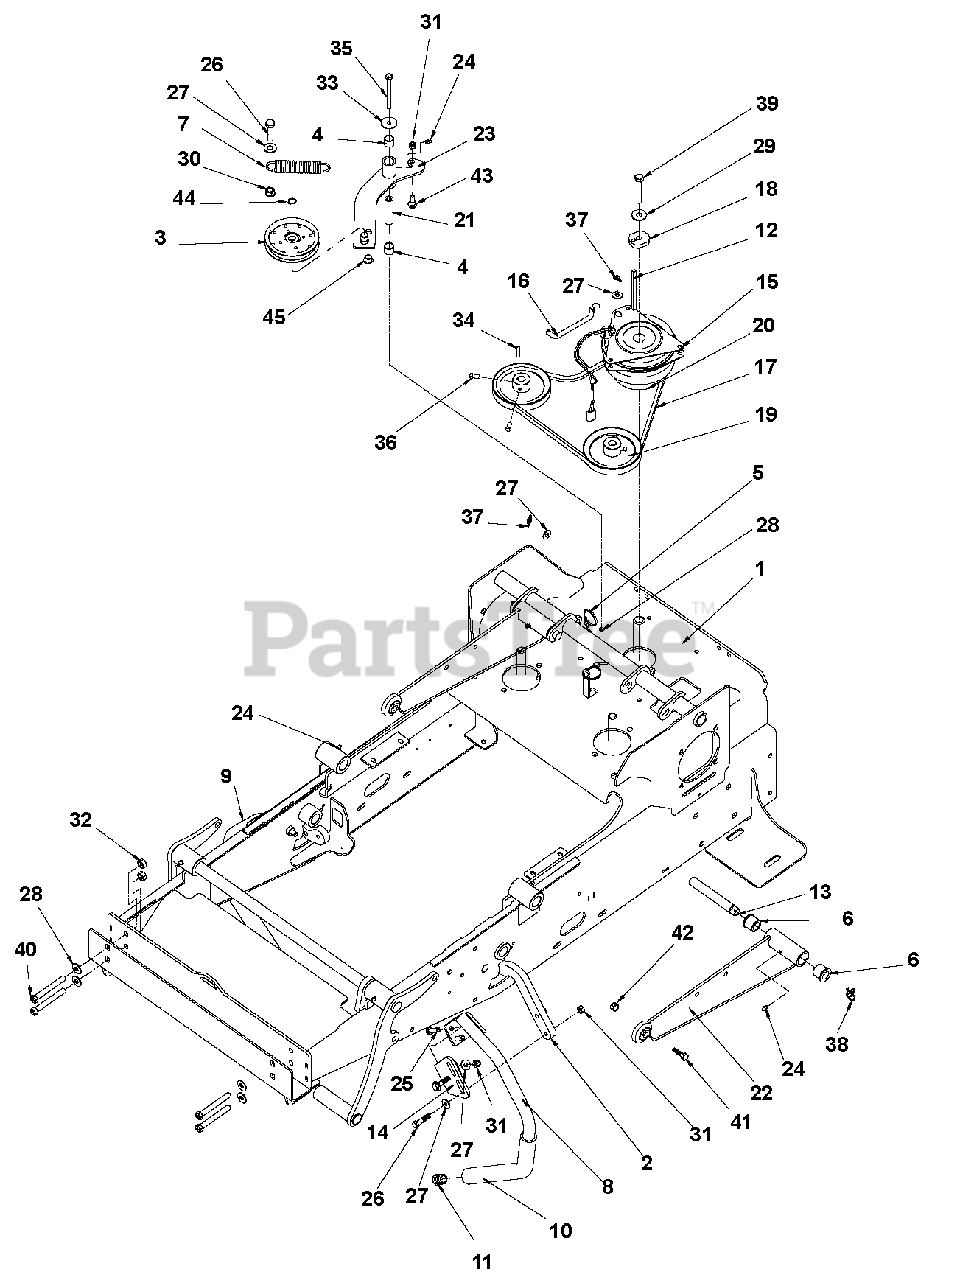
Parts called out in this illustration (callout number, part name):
1	WLDT, FRAME (PAINTED ARIENS)
2	PLATE, STEERING CONTROL
3	PULLEY, FLAT 4.50X.669 W/BRG
4	BRG, SLV .753X.878X.750
5	CABLE TIE, .15 X 8.50
6	BRG, FLG .750X1.13X1.00
7	SPRG, EXTENSION
8	WLDT, LH STEERING HANDLE
9	WLDT, RH STEERING HANDLE
10	FOAM GRIP
11	PLUG, 7/8" END
12	KEY, .250 X .250 X 4.62 SQ
13	PIN, MFG .750X5.38X4.88 XDRL Y
14	PLATE, STEERING CONTROL BENT
15	CLUTCH, ELECT - OGURA GT, 2.5
16	ROD, CLUTCH ANTIROTATION
17	BELT, HA 59.0 OC AMD OHR
18	WASHER, CLUTCH UNIVERSAL W/KEY
19	PULLEY, V-BELT 5.00X.591 W/KEY
20	PULLEY, V-BELT 4.50X1.00 W/KEY
21	TUBE, RD .750 X .156 X 3.05
22	WLDT, DECK PUSH LINK
23	WLDT, HORNET PUMP GEN I RETRO
24	GREASE ZERK, 1/4-28 STR .69 LG
25	BOLT, 3/8-16X1.25 HEX 5 Y
26	BOLT, 3/8-16X1.50 HEX 5 Y
27	@WSHR-FL-STL.38X.875X.083 YWZC
28	@WSHR-FL-STL.438X1.00X.083 YWZ
29	WASHER, .438 REG FLAT Y
30	@NUT-SPNLK-FLG .375-16 YWZC
31	NUT, .38-16 LOW CROWN LK ACORN
32	LOCKNUT, 7/16-14 CROWN Y
33	WASHER, .375X1.50X.063 FLAT Y
34	KEY, M5 X M5 X M30 RD
35	BOLT, 3/8-16X4.00 HEX 5 Y
36	SET SCREW, 5/16-18X.625 SQ CUP
37	RING, RUE .375 X .054 X 1.254
38	RING, RUE .750 X .080 X 2.081
39	BOLT, 7/16-20X2.75 HEX 5 Y
40	BOLT, 7/16-14X3.50 HEX 8 Y
41	BOLT, 1/2-13X2.25 HEX 5 Y
42	LOCKNUT, 1/2-13 CROWN Y
43	BOLT, 1/2X1.06X3/8-16 SLD 5 Y
44	SNAP RING, .672 X .035 EXT
45	BRG, FLG .502X.629X.421
